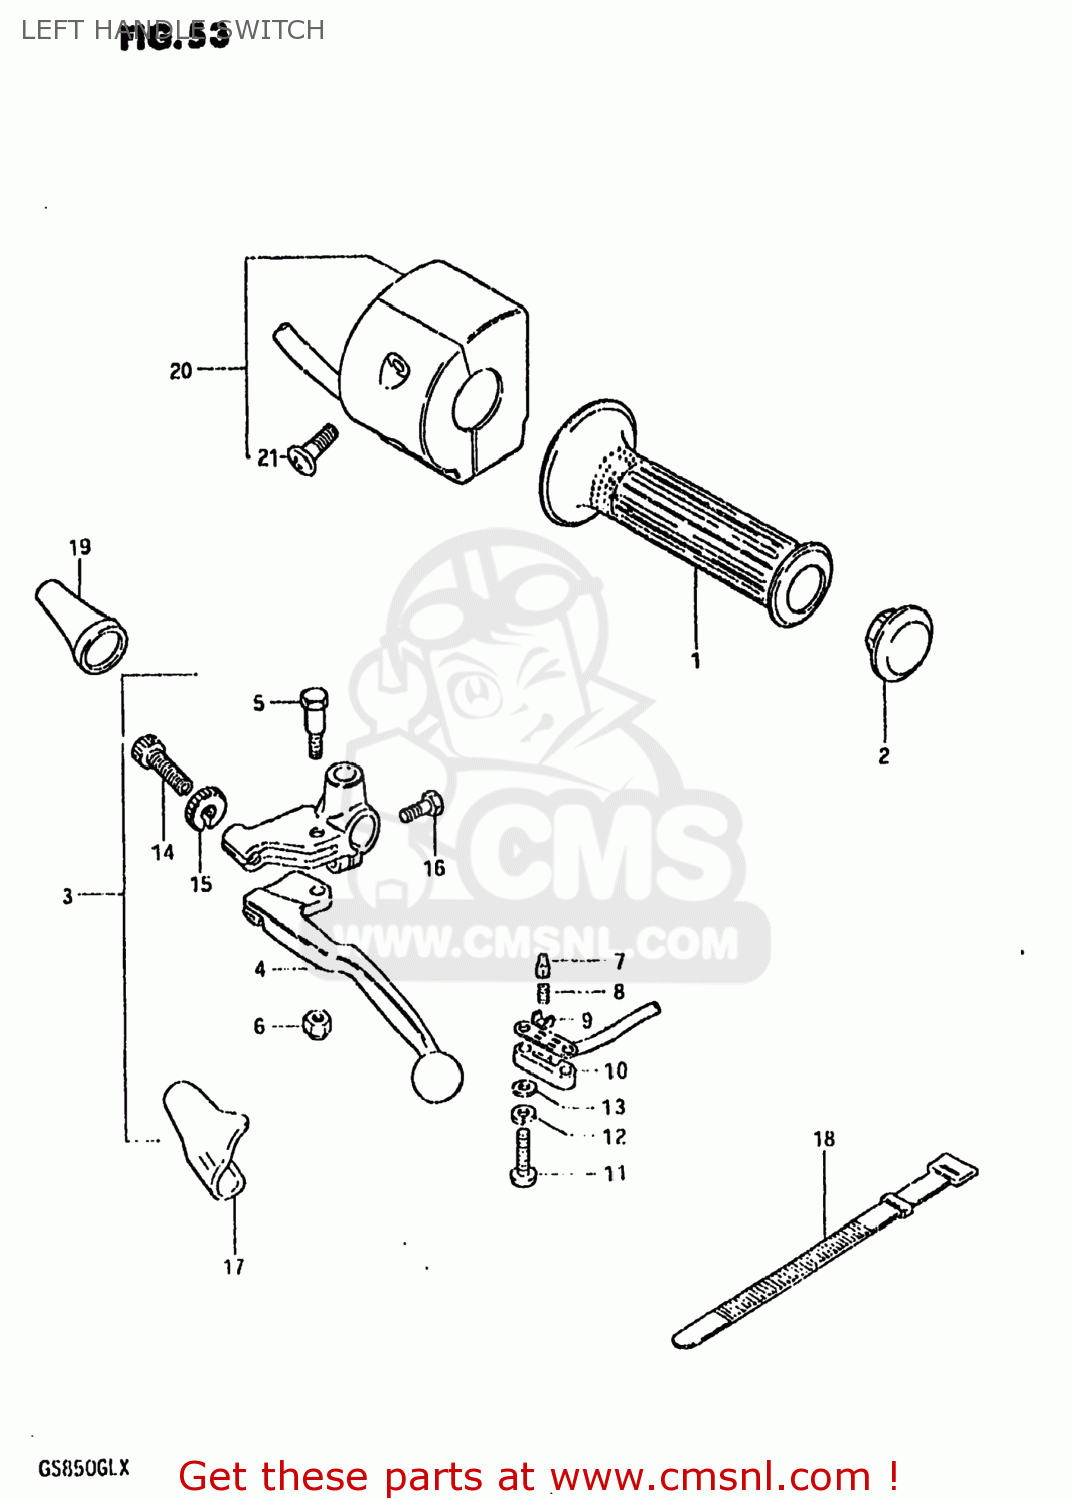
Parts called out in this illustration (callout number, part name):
1	GRIP,LEFT
2	CAP,GRIP END
3	LEVER ASSEMBLY
4	LEVER,CLUTCH
5	BOLT,LEVER
6	NUT 6MM
7	HOLDER
8	SPRING
9	PLATE
10	COVER,FR BK TERMINAL BASE
11	SCREW
12	LOCK WASHER
13	WASHER
14	ADJUSTER,CABLE
15	NUT,CABLE ADJUSTER
16	BOLT,CLUTCH LEVER HOLDER
17	COVER,CLUTCH LEVER
18	CLAMP(L:120)
19	BOOT,CLUTCH CABLE
20	SWITCH ASSEMBLY,HANDLE,LEFT
21	SCREW
